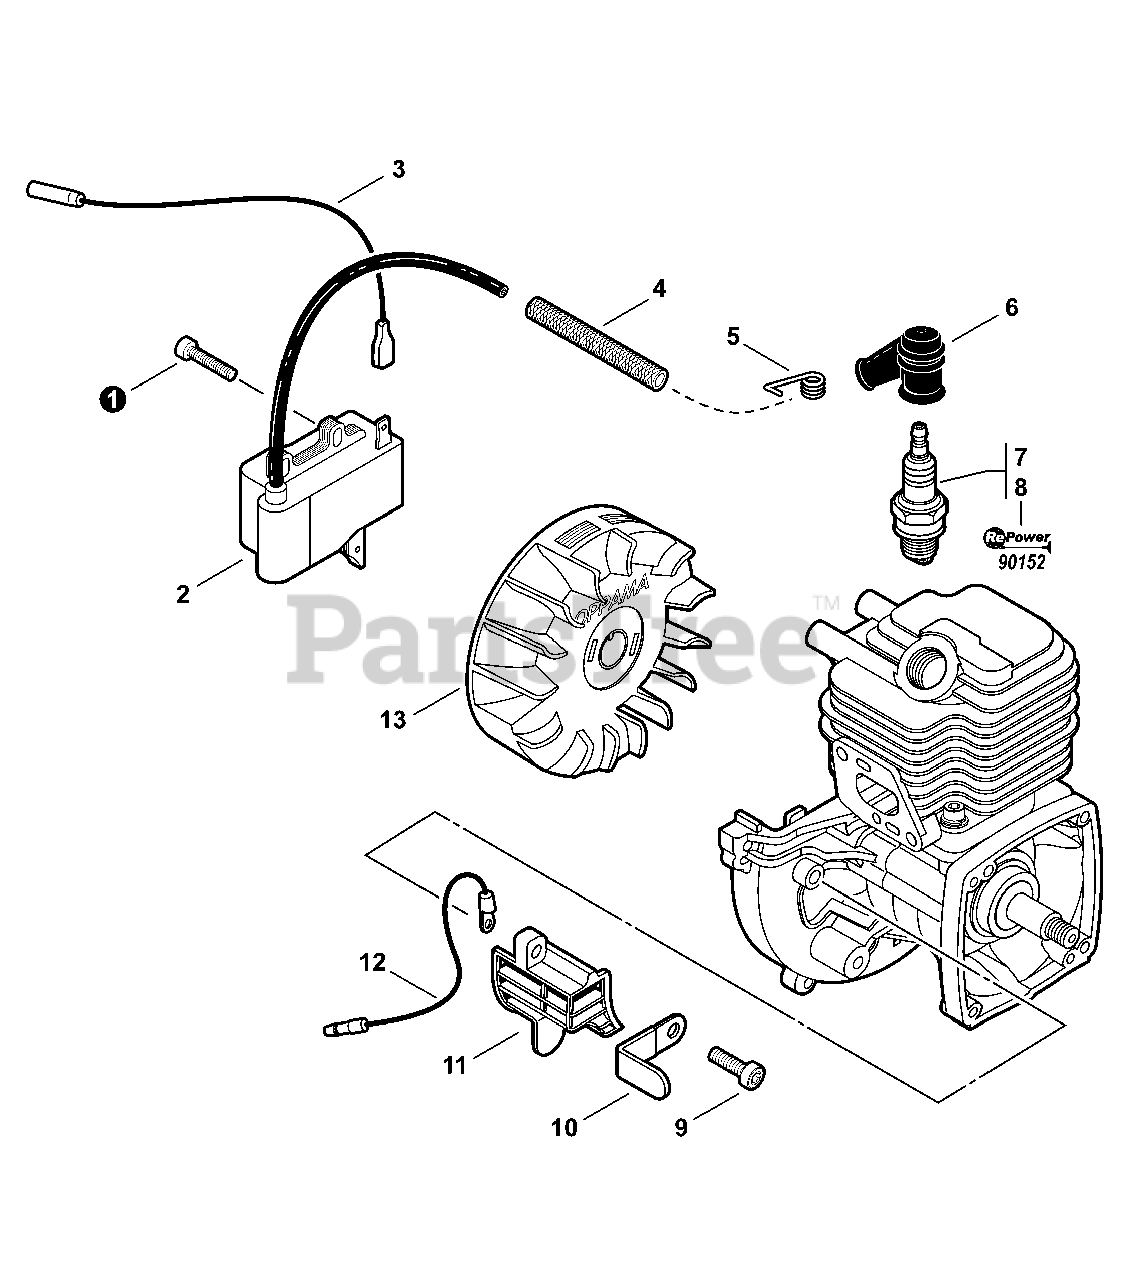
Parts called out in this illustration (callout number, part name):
1	BOLT, TORX 4×20
2	COIL, IGNITION
3	LEAD - IGNITION L= 210
4	TUBE, INSULATOR 7×8.6×65
5	TERMINAL, SPARK PLUG
6	CAP, SPARK PLUG
7	SPARK PLUG - BPM8Y
8	SPARK PLUG - BPMR8Y
9	BOLT, TORX 5×16
11	COVER, DUST
12	LEAD - GROUND
13	FLYWHEEL
